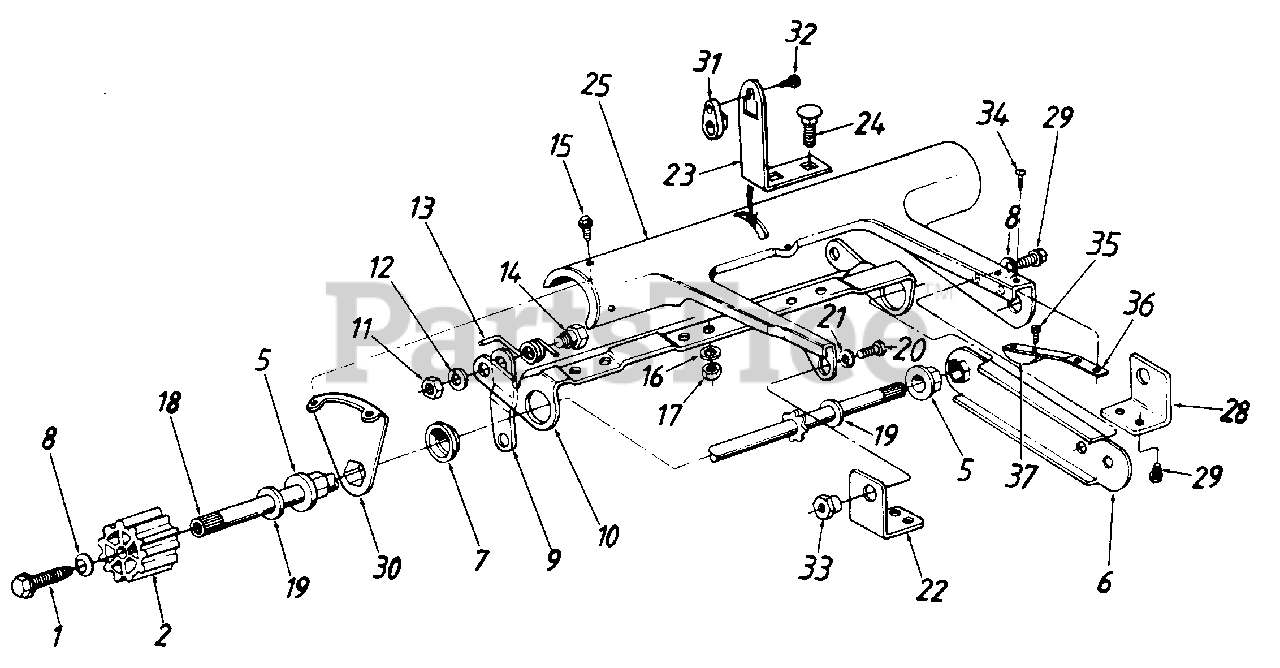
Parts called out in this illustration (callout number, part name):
1	Hex Wash. Hd. Tap Scr. 1/4-20 x .75" Lg.
2	Wheel Drive Pinion
5	Hex Flange Brg. .504" I.D.
8	Bell-Wash. .265" I.D. x .75" O.D.
11	Hex Nut 5/16-18 Thd.
12	L-Wash. 5/16" I.D.*
13	Torsion Spring-R.H.
14	Shoulder Bolt .437" Dia.
15	Hex L-Hd. AB-Tap Scr. 1/4" x .52" Lg.
16	L-Wash. 1/4" I.D.
17	Hex Nut 1/4-20 Thd.
18	Drive Shaft Ass'y.
19	Fl-Wash. .531" I.D. x .93" O.D.
20	Hex Bolt 3/8-16 x .5" Lg.
21	L-Wash. 3/8" I.D.
32	Hex B-Tap Scr. #10 x .44"
33	Shld Nut .625" Dia. x .165" Lg.
34	Truss Mach. B-Tap Scr. #10 x .5" Lg.
35	Hex B-Tap Scr. #10 x 3/8" Lg.
36	Cantilever Spring
37	Chain Tensioner
